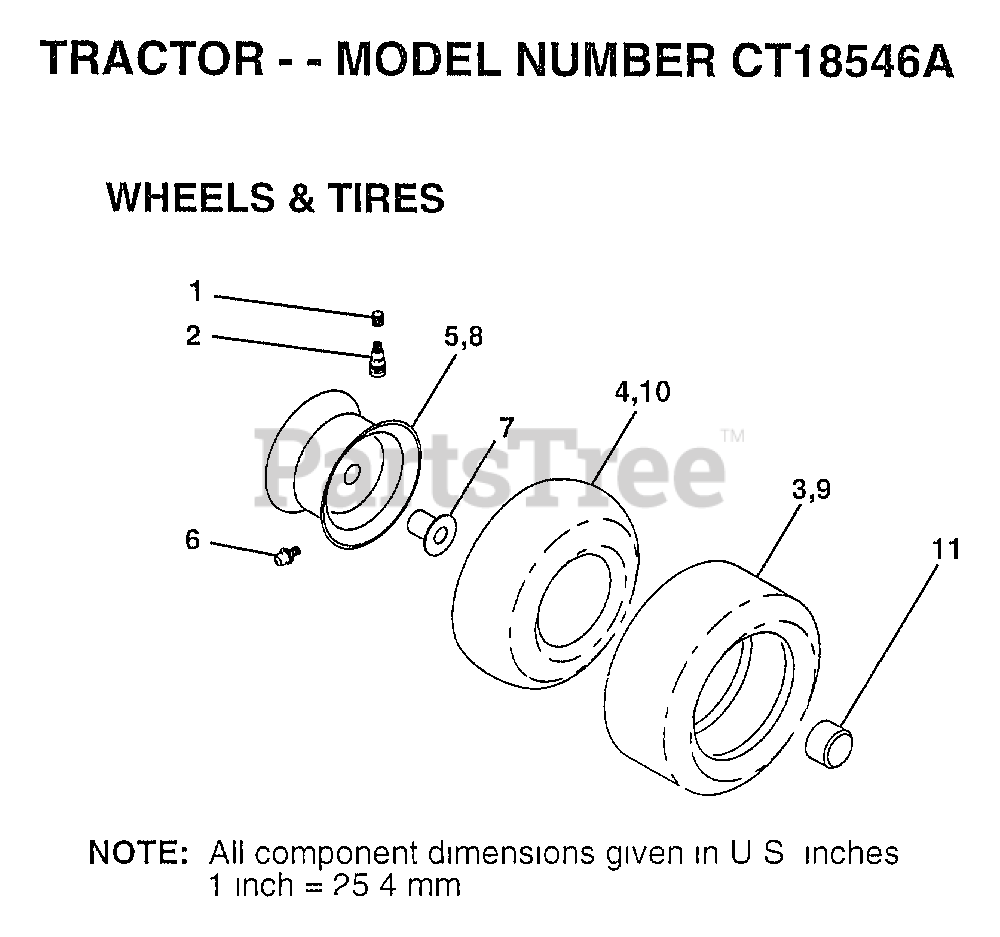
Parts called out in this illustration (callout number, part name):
1	VALVE CAP
2	VALVE STEM LT
4	TUBE.5.3/4.5/6
5	RIM ASSEMBLY, FRONT, 8"
6	FITTING LT
7	"FLANGE, BEARING"
8	RIM ASSEMBLY, REAR, 12"
10	TUBE.23X8/10-12
